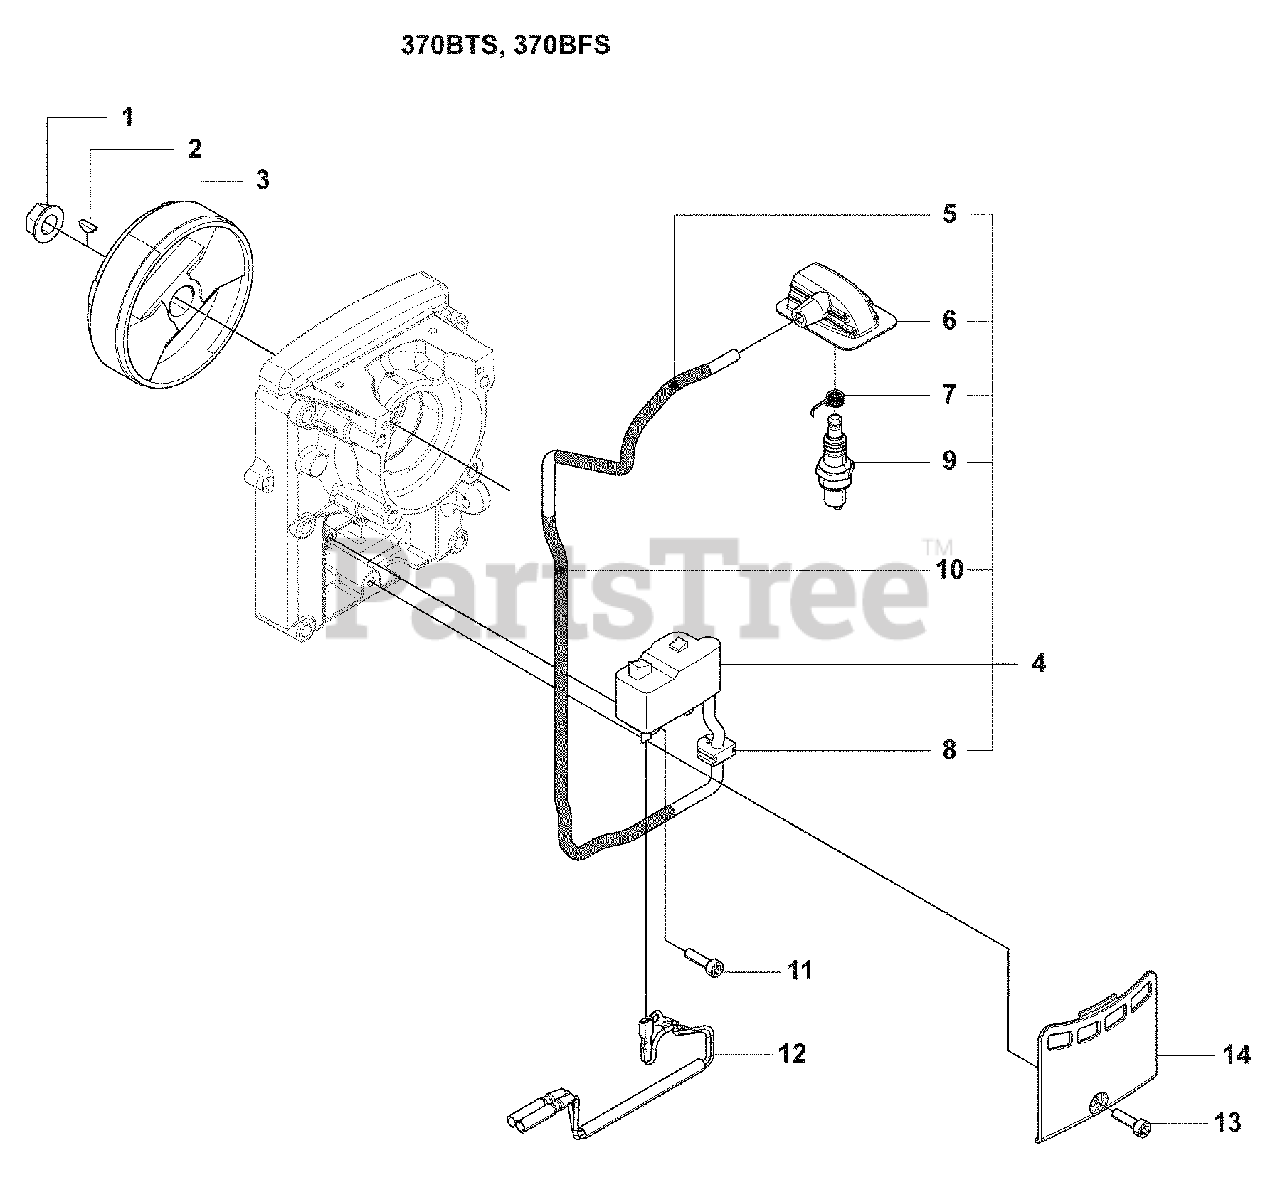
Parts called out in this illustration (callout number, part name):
1	Nut
2	Flywheel Key
4	Ignition Coil
6	Cap
7	Plug Spring
9	Spark Plug, CMR7H BLYB
11	Torx Bolt, M4 X L16
12	Cord, Complete
13	Torx Bolt, M4 X L16
